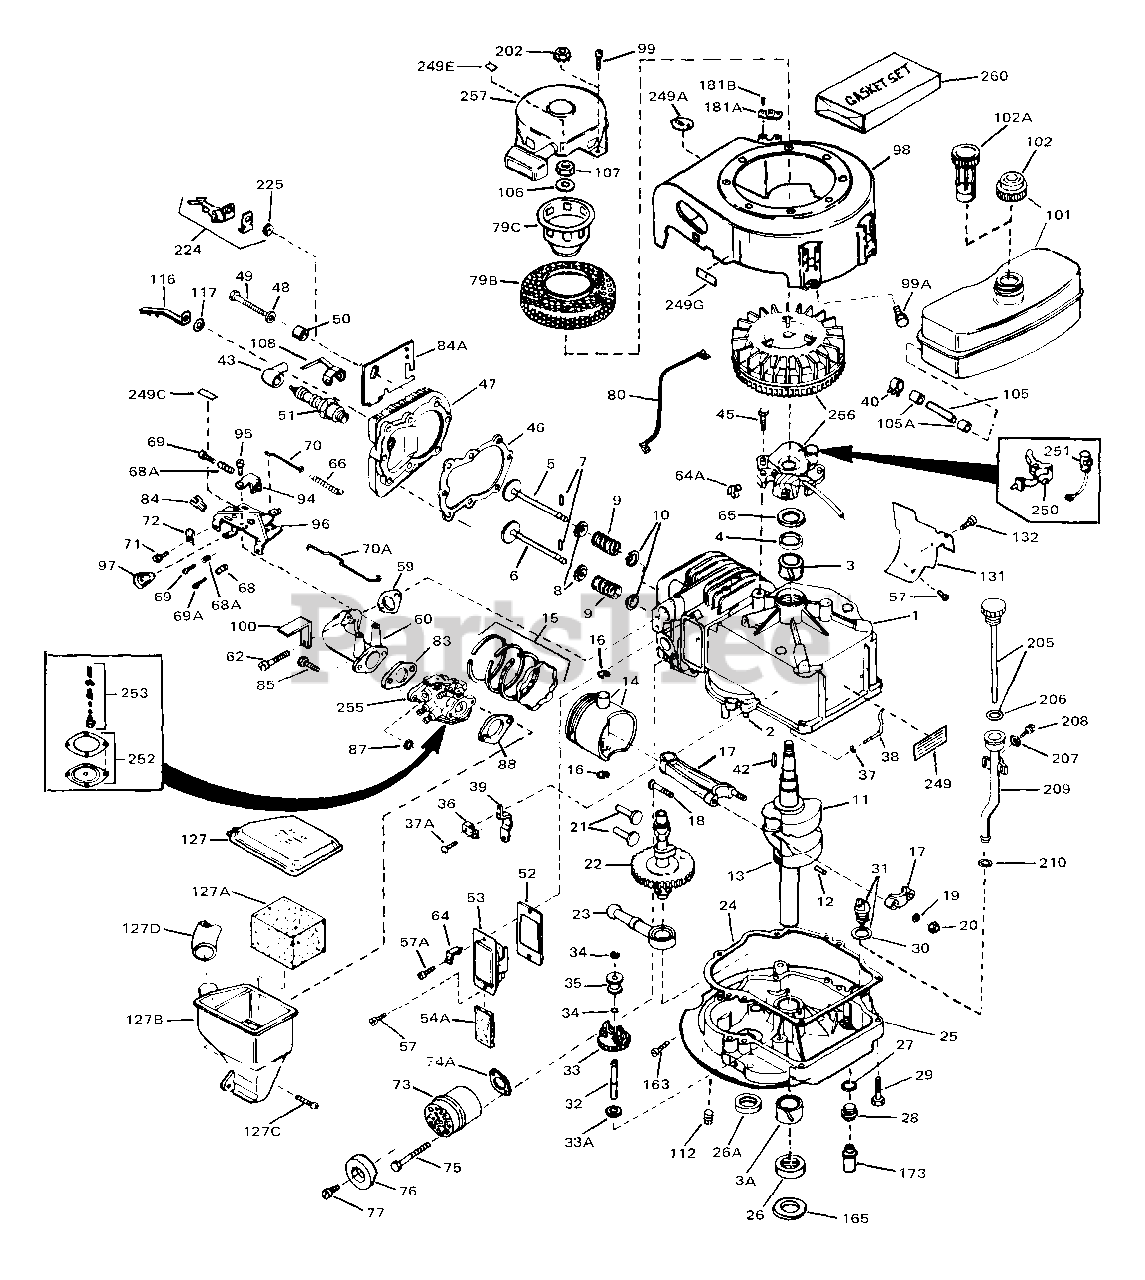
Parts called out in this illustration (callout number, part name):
1	"Cylinder Assy. (2-1/2" Bore)
2	Pin, Dowel
3	Bushing, Crankshaft
3A	Bushing, Crankshaft
4	Seal, Oil
5	Valve, Intake (Standard)
5	Valve, Intake (1/32" oversize)
6	Valve, Exhaust (Standard)
6	Valve, Exhaust (1/32" oversize)
8	Cap, Upper valve spring
9	Spring, Valve
10	Cap, Lower valve spring
11	Crankshaft Assy.
11	Crankshaft Assy. Spec. No. 40475H
14	Piston & Pin Assy. (Standard) (2-1/2" )
14	Piston & Pin Assy. (.010 oversize)
14	Piston & Pin Assy. (.020 oversize)
15	Ring Set, Piston (Standard) (2-1/2")
15	Ring Set, Piston (.010 oversize)
15	Ring Set, Piston (.020 oversize)
15	Re-Ringing Set, Piston
16	Ring, Piston pin retaining
17	Rod Assy., Connecting
18	Bolt, Connecting rod
19	Washer, Connecting rod bolt
20	Nut, Connecting rod bolt
21	Lifter, Valve
22	Camshaft (Compression Release)
23	Pump Assy., Oil
24	Gasket, Mounting flange
25	Flange Assy,, Mounting
26	Seal, Oil
26A	Seal, Oil (Camshaft)
29	Screw, Rd. slotted hd., 1/4-20 x 3/8
29	Screw, Hex hd. Sems, 1/4-20 x 1-1/4
29	Screw, Hex hd. cap, Sems, 1/4-20 x 1- 1/2
30	Gasket, Oil filler
31	Plug, Oil filler
32	Shaft, Mechanical governor
33	Gear Assy., Governor
33A	Washer, Spacer
34	Ring, Retaining
35	Spool, Governor
36	Clamp, Governor lever
37	Washer, Flat
37A	Screw
38	Rod, Governor
39	Lever, Governor
40	Clamp, Fuel line
42	Key, Flywheel
43	Cover, Spark plug
46	Gasket, Cylinder head
47	Head, Cylinder
48	Washer, Flat
49	Screw, Hex hd. cap, 1/4-28 x 7/8
49	Screw, Hex hd. cap, 5/16-18 x 2-3/8
49	Screw, Hex hd. cap, 5/16-18 x 2
49	Screw, Hex hd. cap, 5/16-18 x 2-1/2
51	Plug, Spark (Champion J-8 or equivale nt)
51	Resistor Spark Plug
52	Gasket, Breather cover
53	Breather Assy.
54A	Element, Breather
59	Gasket, Intake pipe
60	Pipe, Intake
64	Clip, Magneto wire
64A	Clip, Lead wire
66	Spring, Governor
66	Spring Governor Spec. No. 40933K
68	Spring Compression
68A	Spring, Compression
69	Screw, Hex hd., 10-32 x 1-5/16" (Dril led
69A	Screw, Slotted fil. hd. mach., 6-32 x 7/16
70	Link, Governor spring
70A	Link, Throttle
71	Screw, Hex hd. slotted Sems, 10-32 x 3/8
72	Clip, Conduit
74A	Gasket, Exhaust
75	Screw, Hex hd. cap, 1/4-20 x 3-3/8
75	Screw, Hex hd. cap, 1/4-20 x 2-1/2
75	Screw, Hex hd. cap, 1/4-20 x 3
75	Screw, Hex hd. cap, 1/4-20 x 2-3/4
75	Screw, Hex hd. cap, 1/4-20 x 2-1/4
75	Screw, Hex hd. Sems, 1/4-20 x 1-3/4
75	Screw, Hex hd. cap, Sems, 1/4-20 x 2- 5/16
80	Wire, Ground (Female fittings both en ds)
83	Gasket, Carburetor (1/32" thick)
83	Gasket, Carburetor (1/8 thick)
84	Terminal
85	Screw, Hex hd. cap, 1/4-28 x 7/8
85	Screw, Hex hd. cap, 1/4-28 x 1
85	Screw & Lockwasher, Hex hd. cap, 1/4- 20 x 1
87	Nut & Lockwasher Assy.
88	Gasket, Air cleaner
94	Bracket, Control
95	Screw & Lockwasher, Hex hd. self-tapp ing,
96	Control Assy., Speed
98	Housing, Blower
99	Screw, Fil. slotted hd., 1/4-28 x 5/8
99	Screw, Phil. oval hd. w/lockwasher, 1 /4-28 x
99	Screw, Phil. pan hd. Sems, 1/4-28 x 7 /16
99	Screw, Phil. oval hd. Sems, 1/4-28 x 2-3/8
99	Screw & Lockwasher, Fil. hd. P.C.R. m ach.,
99	Screw, Hex hd. cap Sems, 1/4-20 x 1/2
99	Screw, Hex washer hd. taptite, 1/4-20 x 1/2
99A	Screw, Phil. hex hd. Sems, 1/4-20 x 5 /8
100	Clip, Fuel line
101	Tank Assy., Fuel (White Poly) (1 qt.)
102	Cap, Fuel filler (Red Plastic) (Sno P roof)
102	Cap, Fuel filler (Charcoal Plastic) ( Spurt
102	Cap, Fuel filler (White Plastic) (Sta ndard)
102	Cap, Fuel filler (Metal, w/chain)
105	Line, Fuel (7-3/8" Metal)
105	Line, Fuel (3-3/8" Metal)
105A	Line, Fuel (Braided hose) (14-5/8")
105A	Line, Fuel (Braided hose) (8-1/4")
105A	Line, Fuel (Braided hose) (16")
105A	Line, Fuel (Braided hose) (32")
106	Washer, Belleville
107	Nut, Flywheel
112	Plug, Oil drain (Sq. hd. pipe, 1/8-27 )
116	Clip, Spark plug shorting
117	Lockwasher, 5/16
127	Cover, Air cleaner
127A	Element, Air cleaner
127B	Body, Air cleaner
127D	Tube, Air cleaner
132	Screw
163	Screw, Hex washer hd. thread-forming, 10-24
165	Cap, Oil seal protector
173	Extension, Oil drain
181B	Rivet, Open end
206	"O" Ring
207	Washer, Flat
208	Screw, Slotted Hex hd. S.T. Sems, 10- 32 x
210	"O" Ring (.614 I.D. x .750 O.D. x .07
210	"O" Ring (.612 I.D. x .812 O.D. x .10 3
249	Decal, Name & Instructions
249A	Decal, H.P. (3 H.P.)
249A	Decal, H.P. (3-1/2 H.P.)
249A	Decal, Name & H.P. (3 H.P.)
249A	Decal, Name & H.P. (3-1/2 H.P.)
249E	Decal, Ezee Start
249E	Decal, Starter
249E	Decal, Super Start
249G	Decal, Choke
250	Contact Assy., Breaker
251	Condenser
252	Diaphragm Assy.
253	Inlet Needle, Seat, Gasket & Spring A ssy.
255	Carburetor
256	Magneto, Tecumseh (w/ring gear)
260	Gasket Set
